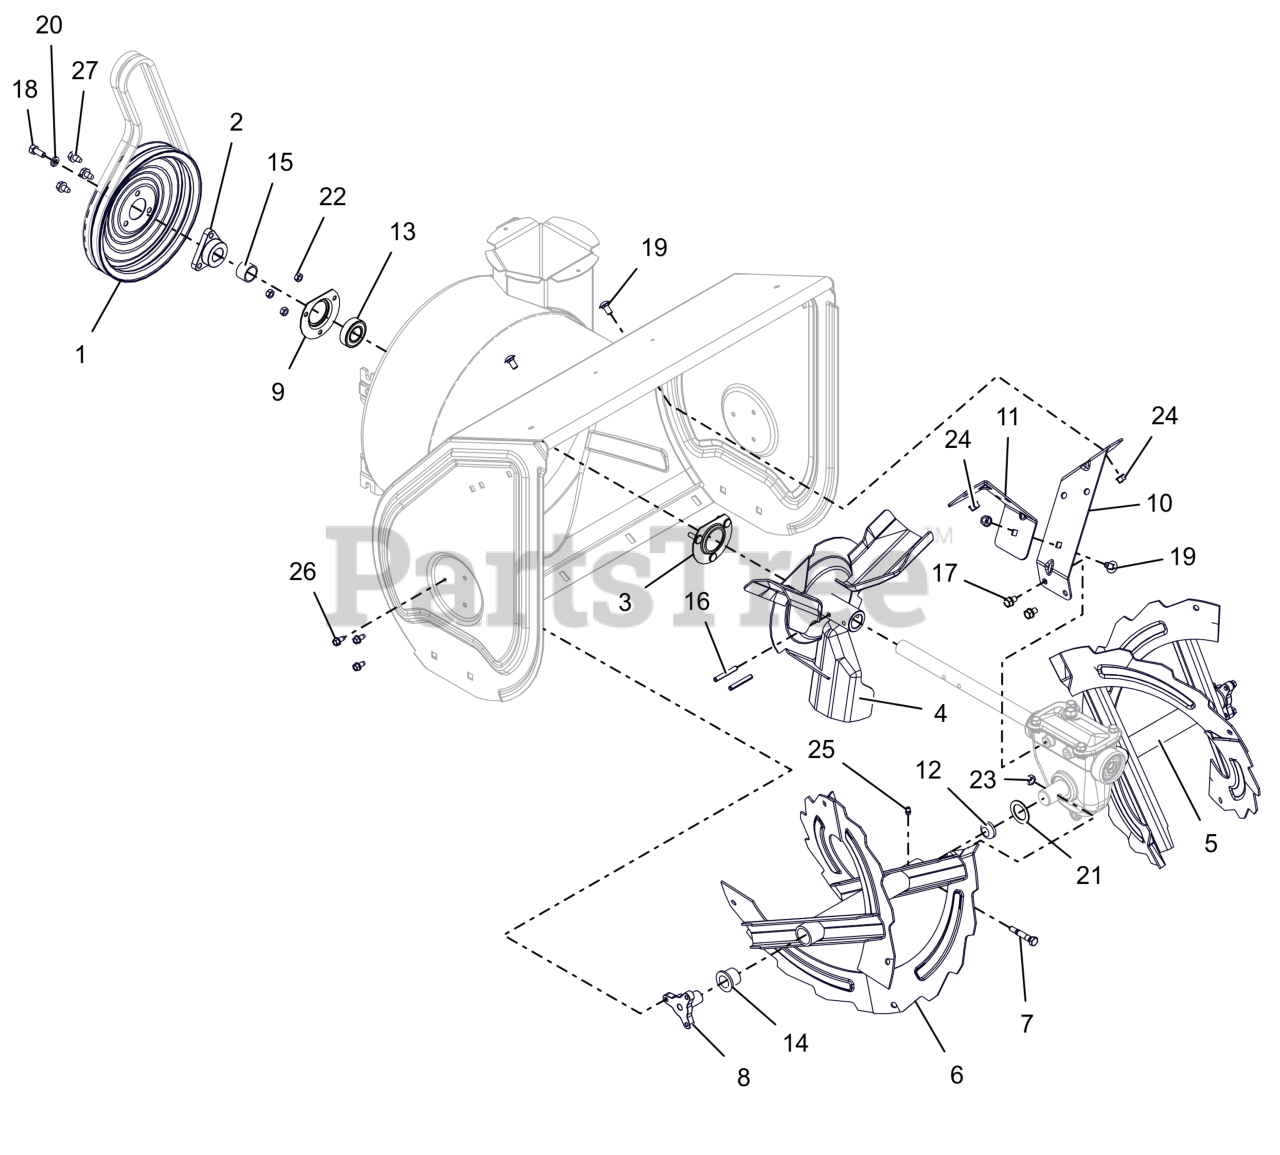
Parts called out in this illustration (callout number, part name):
1	PULLEY, SPIN FORM DUAL GROOVE
2	PULLEY HUB, D-BORE .87 PRO
3	BEARING FLANGE
4	IMPELLER, 3 BLADE-14"
5	RAKE, LH W/ZERK - 24"
6	RAKE, RH W/ZERK - 24"
7	SHEAR BOLT SERVICE ASSEMBLY
8	SUPPORT, RAKE BUSHING
9	BEARING FLANGE
10	BRACKET, GEARCASE SUPPORT - LH
11	BRACKET, GEARCASE SUPPORT - RH
12	PLUG, RAKE TUBE
13	BRG-BALL .876 X 1.750 X .50
14	BSHG-FLG, NY.778 ID X 1.018 OD
15	BSHG,SPCR .895X1.065X.693
16	PIN-ROLL .250X1.75
17	BLT, SEMS .31-18X.50 G5 ZCC
18	BLT, HEX .31-24X.750 G5 ZCC
19	BLT,RHSSN.31-18X.625 G5 ZCCP30
20	WSHR, LK-HVY .312X.097 ZCC
21	WSHR, FLT 1.010X1.505X.062 ZCC
22	NUT,LK-CTR .25-20 GA ZCC
23	NUT,LK-CTR .31-18 GA ZCC
24	NUT-LK-TOP-FLG .312-18 GF ZCC
25	ZERK,FITTING .25X.125 DRIVE IN
26	SCR-TAP .25-20X.50 HWH ZCC
27	SCR,TAP .312-18X.50 HWH TR ZCC
